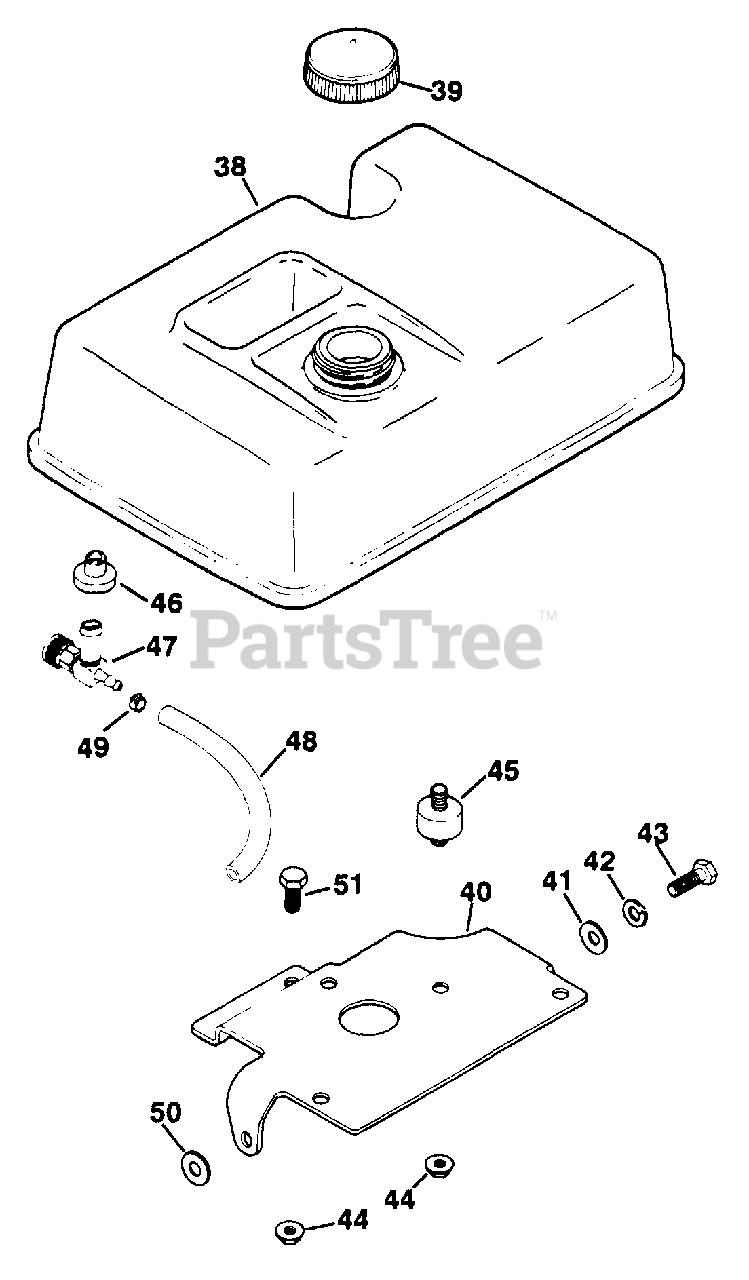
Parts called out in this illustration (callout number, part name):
38	TANK - DISCONTINUED
40	BRACKET - DISCONTINUED
41	WASHER, FLAT 1/4" (O.D. 5/8")
42	WASHER, SPRING LOCK 1/4"
43	SCREW - DISCONTINUED
44	PALNUT, 1/4-20
45	MOUNT, ISOLATION - (#DSC)
49	CLAMP, HOSE
50	WASHER, FLAT 1/4" (O.D. 1")
51	SCREW,HEX CAP - DISCONTINUED
